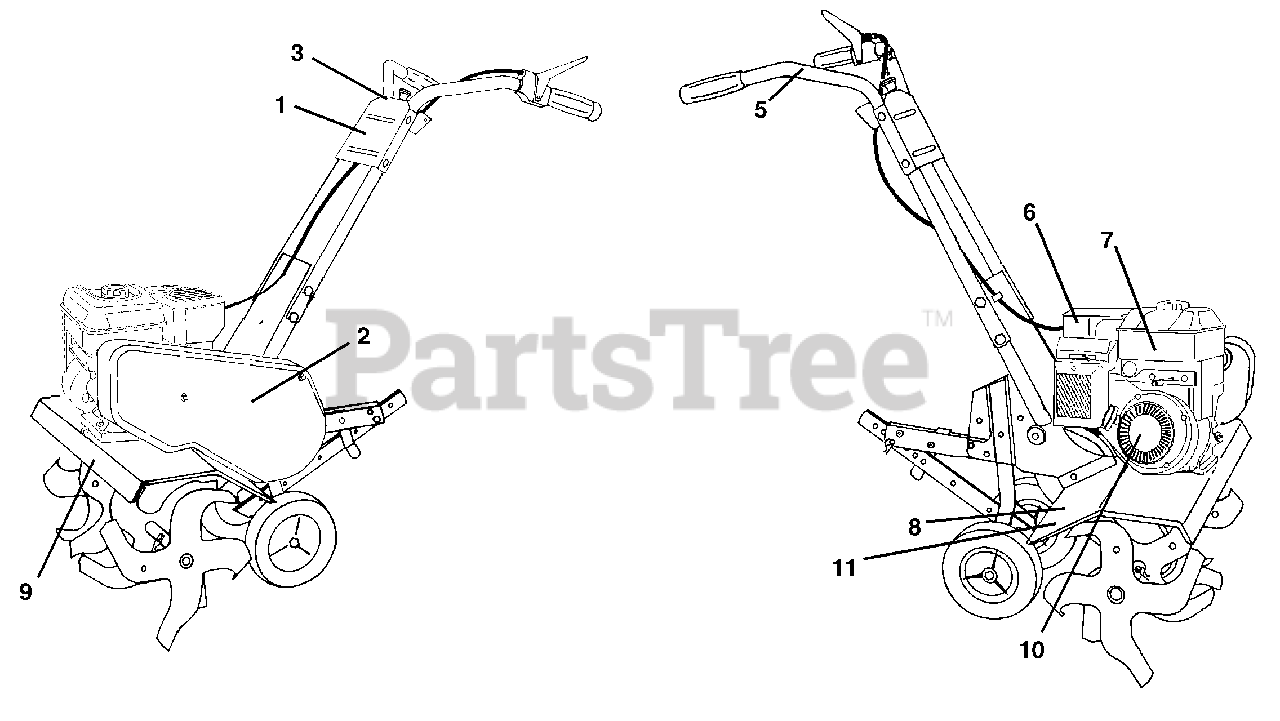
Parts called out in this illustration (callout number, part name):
1	Decal, Logo
2	Decal, Logo
3	Decal, Control Panel
5	Decal, Hand Placement
6	Decal, Eng. Tiller
7	Decal, OHV. N-I/C
8	Decal, Warning, Rotating Tines
9	Decal, Tine Shield
10	Decal, Rewind Intek
11	Decal, Tine Shield Wrng. Dom
